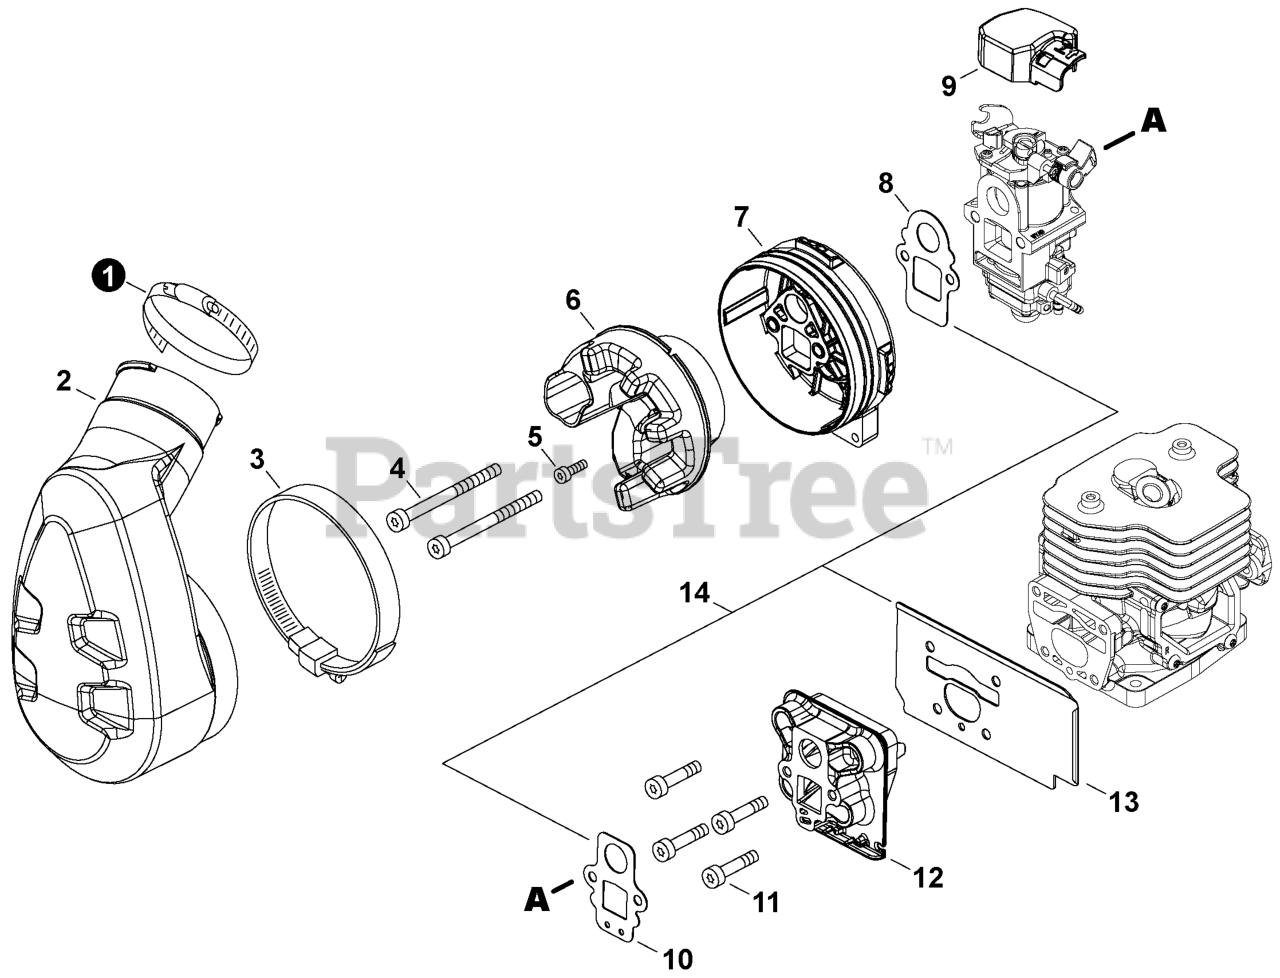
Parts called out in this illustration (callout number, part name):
1	CLAMP - BAND 33 MM /57 MM
2	ADAPTOR, AIR FILTER
3	CLAMP - BAND 77.8 MM / 101.6 MM
4	BOLT, TORX 5x65
5	BOLT, TORX 4x12
6	DUCT, AIR
7	BRACKET, AIR FILTER
8	GASKET, INTAKE
9	CAP, CARBURETOR
10	GASKET, INTAKE
11	BOLT 5x25
12	INSULATOR, INTAKE
13	HEAT SHIELD, INTAKE
14	GASKET KIT: ENGINE, INTAKE, EXHAUST
